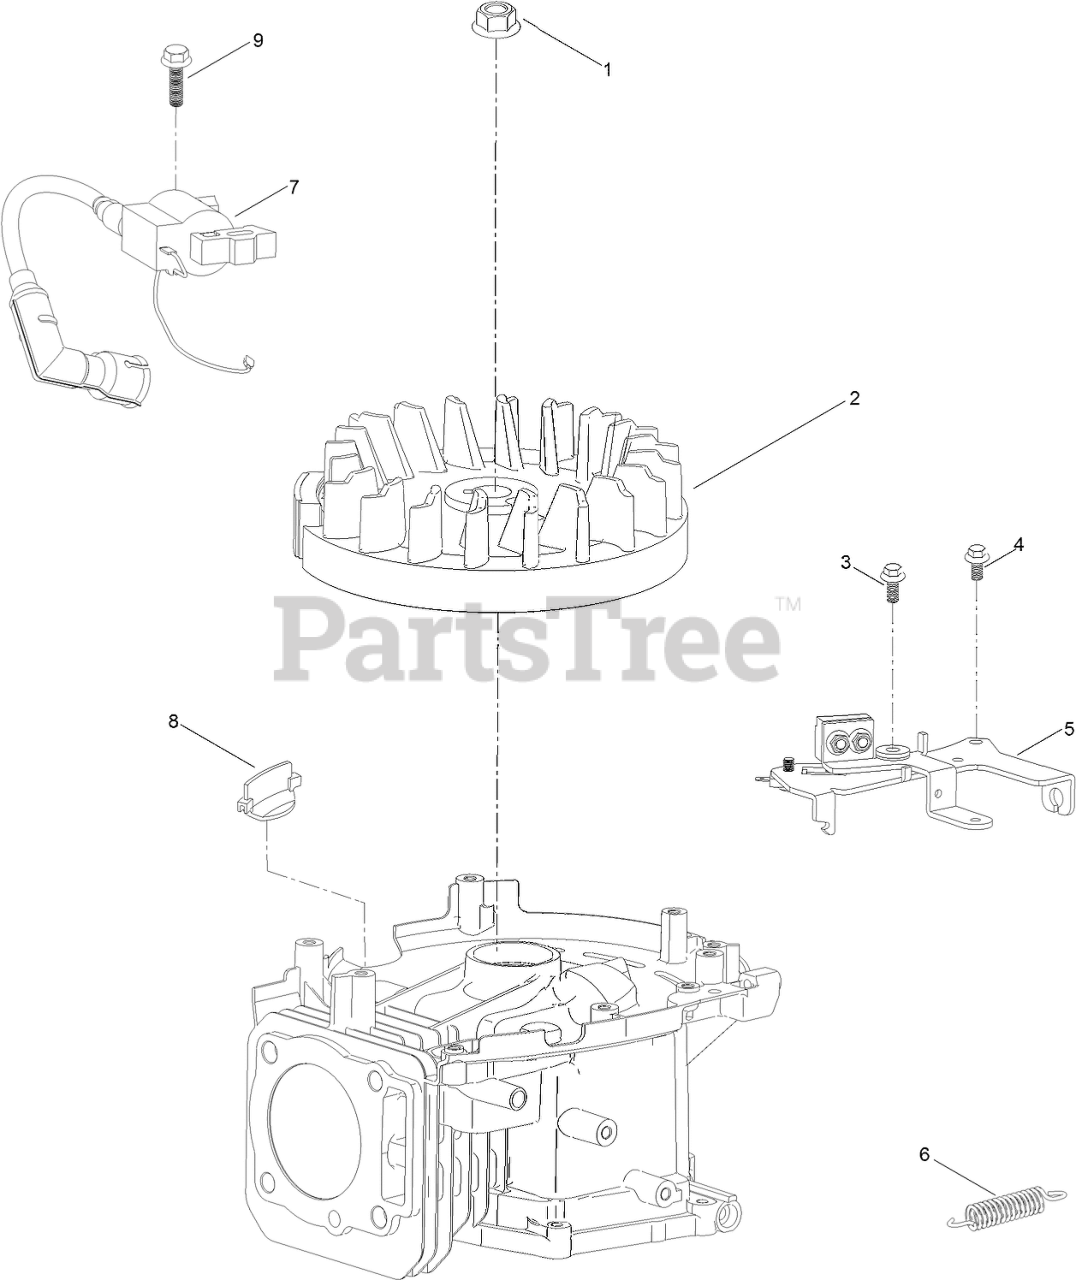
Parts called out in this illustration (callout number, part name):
1	NUT-FLANGE
2	FLYWHEEL
3	BOLT-FLANGE
4	SCREW-HHF
5	BRAKE ASM
6	SPRING-BRAKE
7	IGNITION COIL ASM
8	GUARD-FLYWHEEL
9	SCREW-HHF
